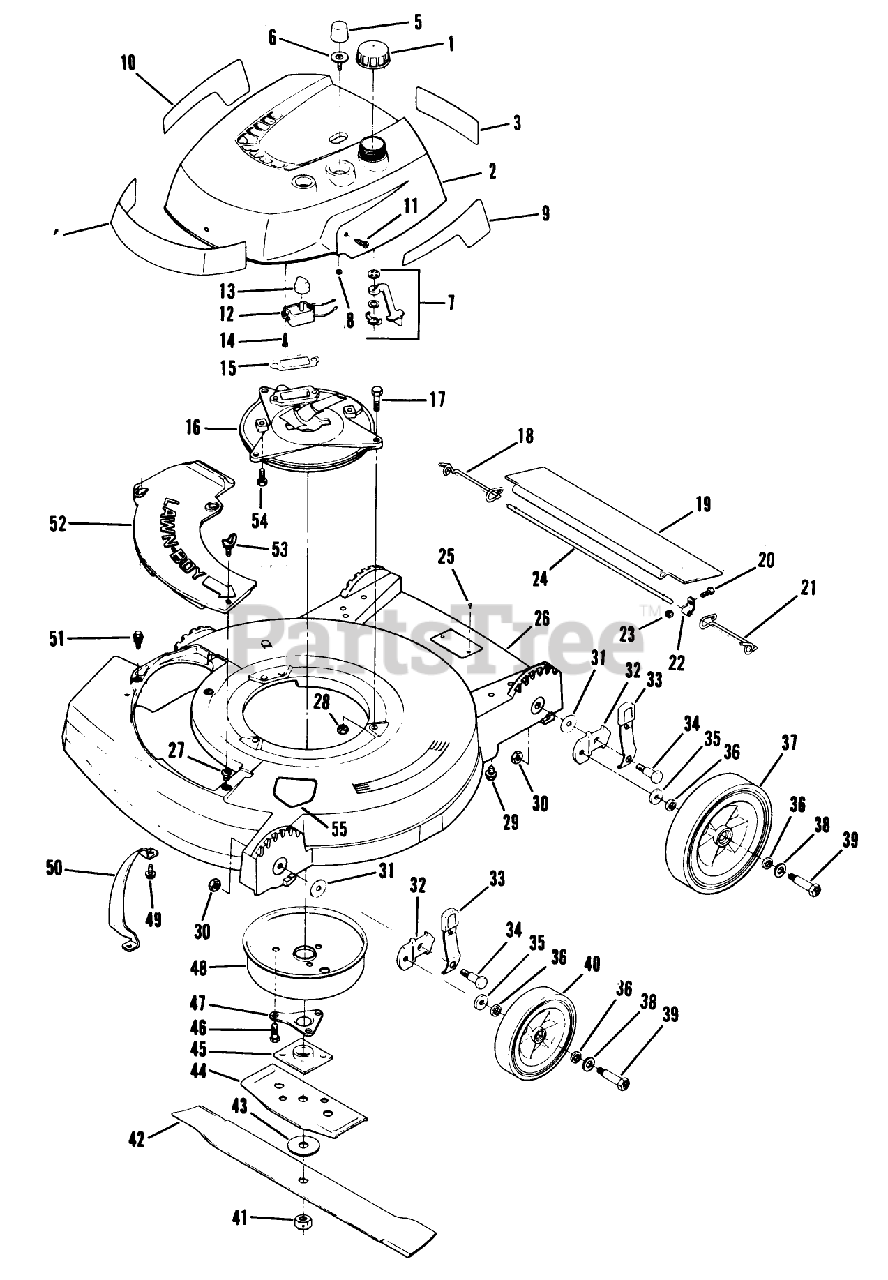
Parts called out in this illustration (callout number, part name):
8	LOCKNUT S
10	DECAL
11	SCREW S
13	SWITCH KNOB
18	SPRING;TRAILING SHIELD RH
19	TRAILING SHIELD-19
21	SPRIG T/SHLD ASOC
22	CLAMP ROD KMC
23	LOCKNUT E
24	ROD T/SHIELD ADV WIRE
24	ROD 21" ADVANCE
28	NUT-LOCK F
30	LOCKNUT
35	WASHER WROUGHT
39	BOLT WHEEL
40	WHEEL & TIRE KIT
41	NUT-BLADE
45	PLATE AND COLLAR ASM
47	SUPPORT F
50	TOE BAR 19"
50	BAR-TOE
52	COVER PLATE
53	WING SCREW LAWRE
54	SCREW V
